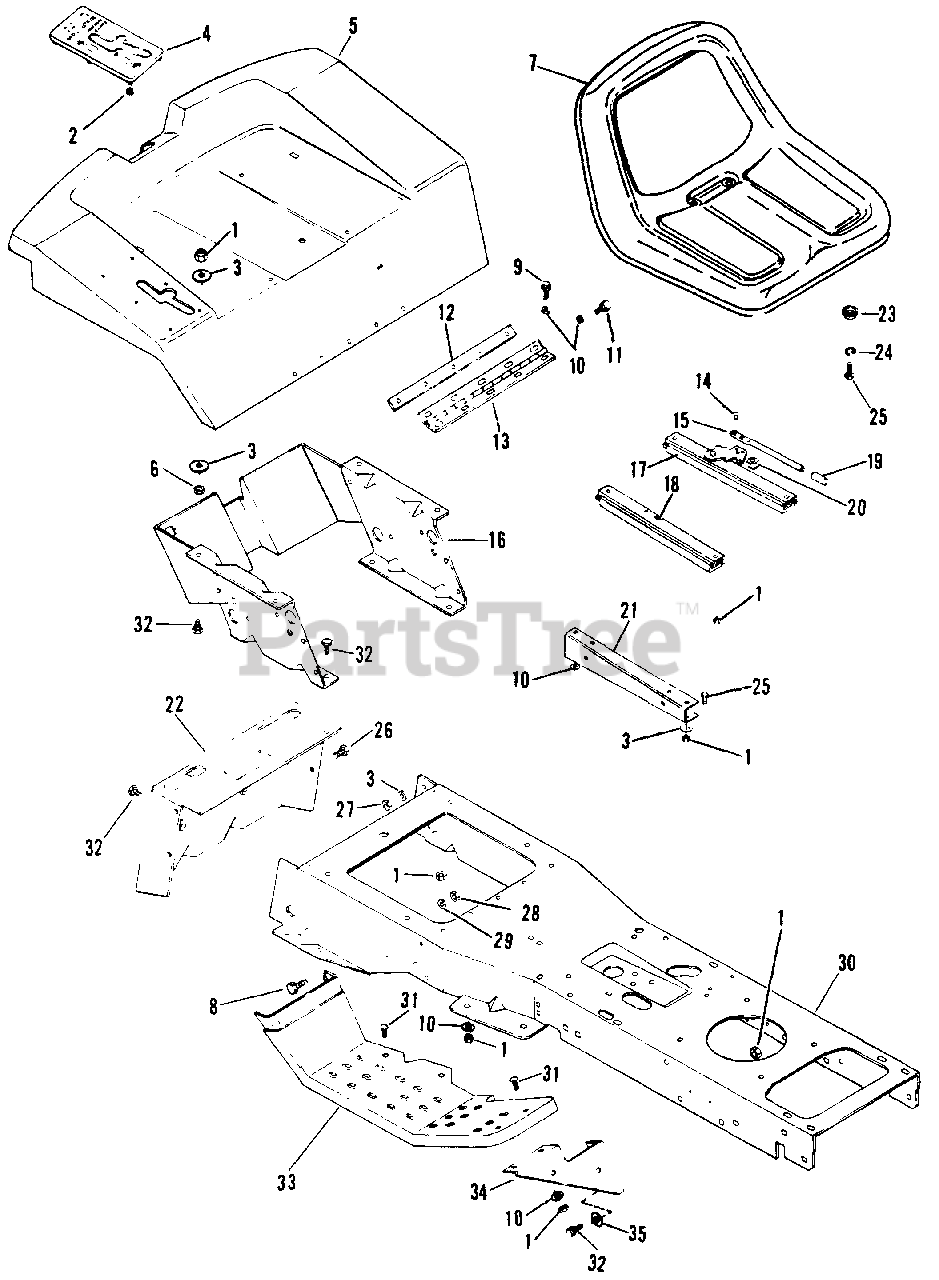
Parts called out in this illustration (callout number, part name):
1	Nut, Lock 5/16-18
2	Palnut, 1/4
3	Washer, Flat .375 x 1.125 x .065
4	Speed Selector Insert
5	Deck, Rear
6	Nut, Hex 5/16-18
7	Seat, High Back
8	Bolt, Hex 1/4-20 x .750
9	Screw, Taptite 5/16-18 x .75
10	Washer, Flat .344 x .688 x.065
11	Screw, Taptite 5/16-18 x .50
12	Strap
13	Hinge
14	Screw, Mach. 10-24 x .625 PHD
15	Handle, Seat Slide
16	Deck, Support
17	Adjuster, Seat w/Latch
18	Adjuster, Seat
19	Tips, Brake Lock Lever
20	Nut, Lock 10-24
21	Spacer, Seat
22	Weldment, Tailboard
23	Bushing, Flange Steel
24	Washer, Lock 5/16 Reg.
25	Bolt, Hex 5/16-18 x .75
26	Bolt, Hex 3/8-16 x .875
27	Nut, Lock 3/8-16
28	Nut, Lock 1/4-20
29	Washer, Flat .281 x .625 x .065
30	Frame
31	Bolt, Carriage 5/16-18 x 1.0
32	Bolt, Hex 5/16-18 x 1.00
33	Foot Rest, R.H.
33	Foot Rest, L.H.
34	Foot Rest Brace, R.H.
34	Foot Rest Brace, L.H.
35	Washer, Flat .313 x .875 x .065
